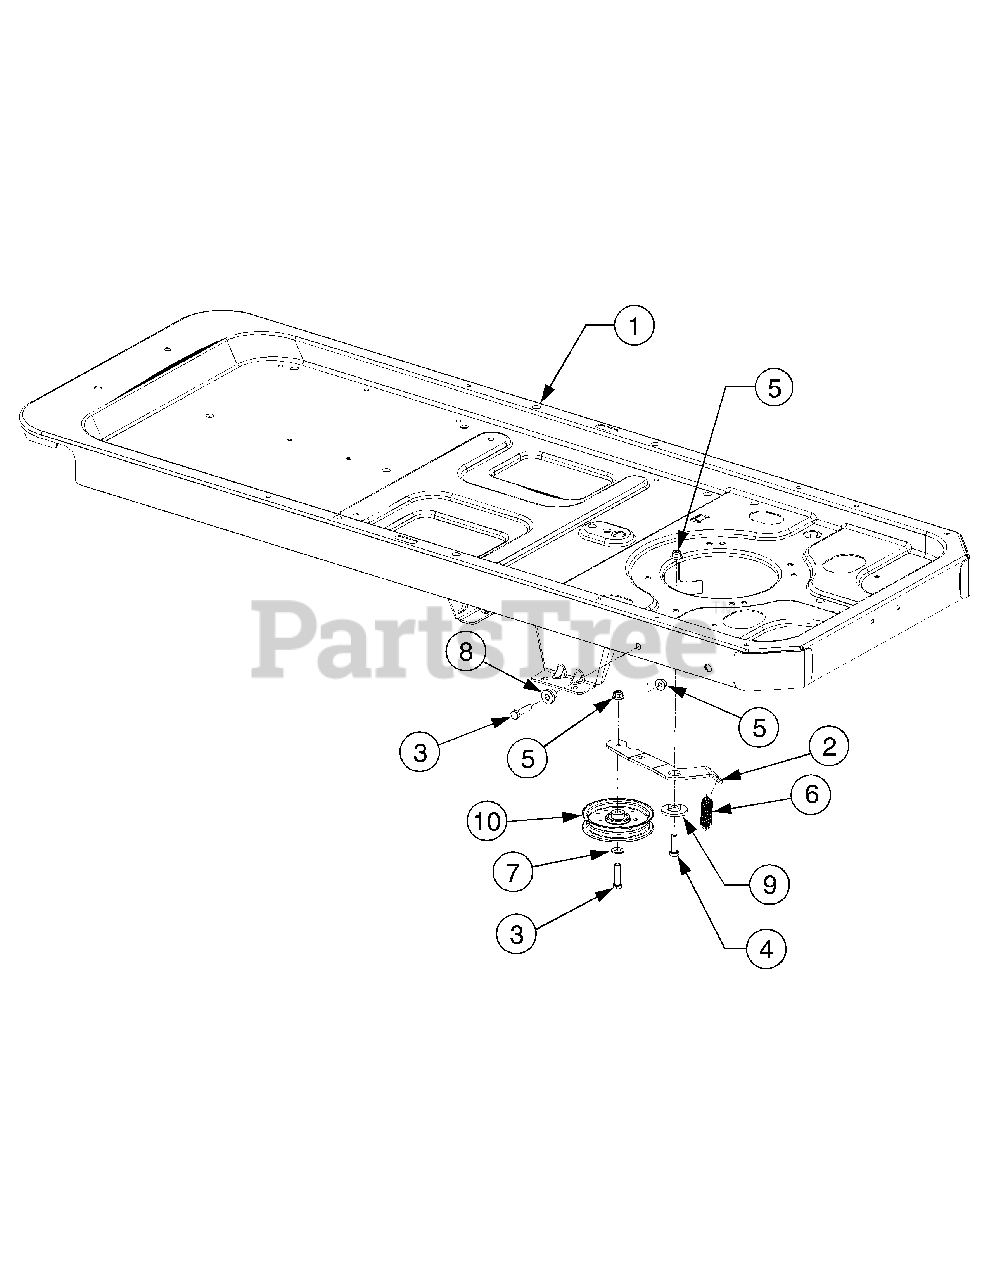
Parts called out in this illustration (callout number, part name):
1	Graphic, Cub Cadet
1	Graphic, Release Lever
3	Screw, Hex Cap, 3/8-16 x 1.5 GR5
4	Screw, Hex Cap, 3/8-16 x 1.25 GR5
5	Nut, Hx Insert Flnge Lck, 3/-16 GrF
6	Spring, Extension, .75 x 5.06
7	Washer, Flat, .408 x .875 x .059
8	Spacer, Shoulder, .39 x 1.0 x .7
9	Spacer, Shoulder, .884 x .19
10	Pulley, Idler, 4.25 Dia.
